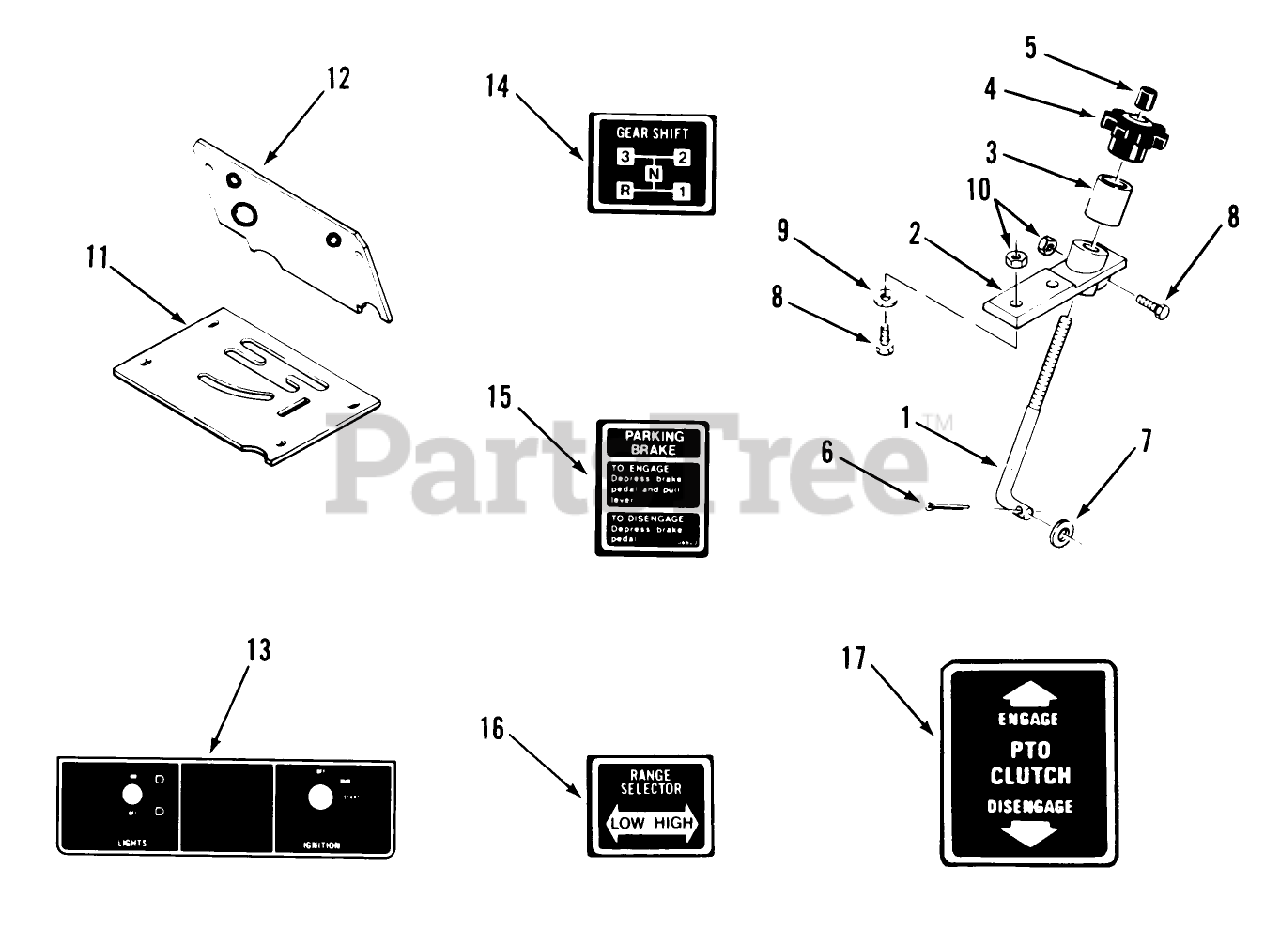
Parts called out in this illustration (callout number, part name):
1	Rod
2	Casting
3	Sleeve
4	KNOB-LIFT CONTROL
5	CAP-ROD, PLUNGER
6	Pop Rivet
7	WASHER -4
8	Bolt
9	WASHER 5/16 SAE
10	Nut
11	PLATE-SHIFT PATTE B
12	PLATE HOODSTAND B
13	DECAL-BACK PLATE-SWI
14	DECAL-SHIFT
15	DECAL-PARKING BRAKE
16	DECAL HI-LO
17	DECAL-PTO CLUTCH
